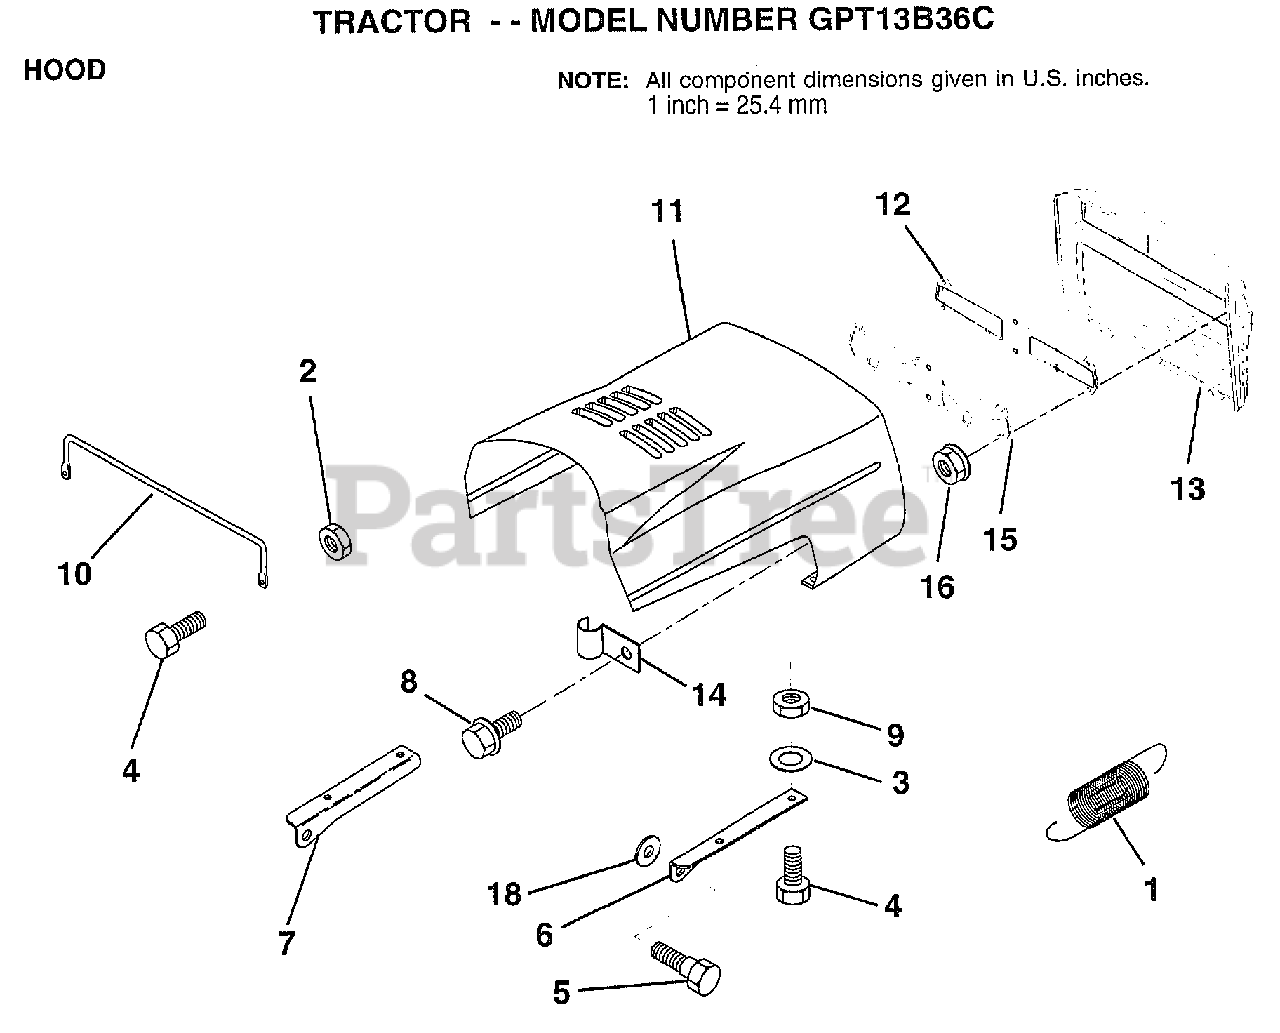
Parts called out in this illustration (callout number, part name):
1	EXT SPRING
2	NUT
3	WASHER
5	BOLT.SHLD.5/16-18
6	BRKT HOOD RH
7	BRKT HOOD LH
8	"SCREW,HWHD.HI-LO#13-16X3/4"
9	NUT
10	"BRACE,HOOD"
11	HOOD.IMPREG.MS550
13	GRILLE.P/L.MOLDED
16	NUT
18	WASHER
